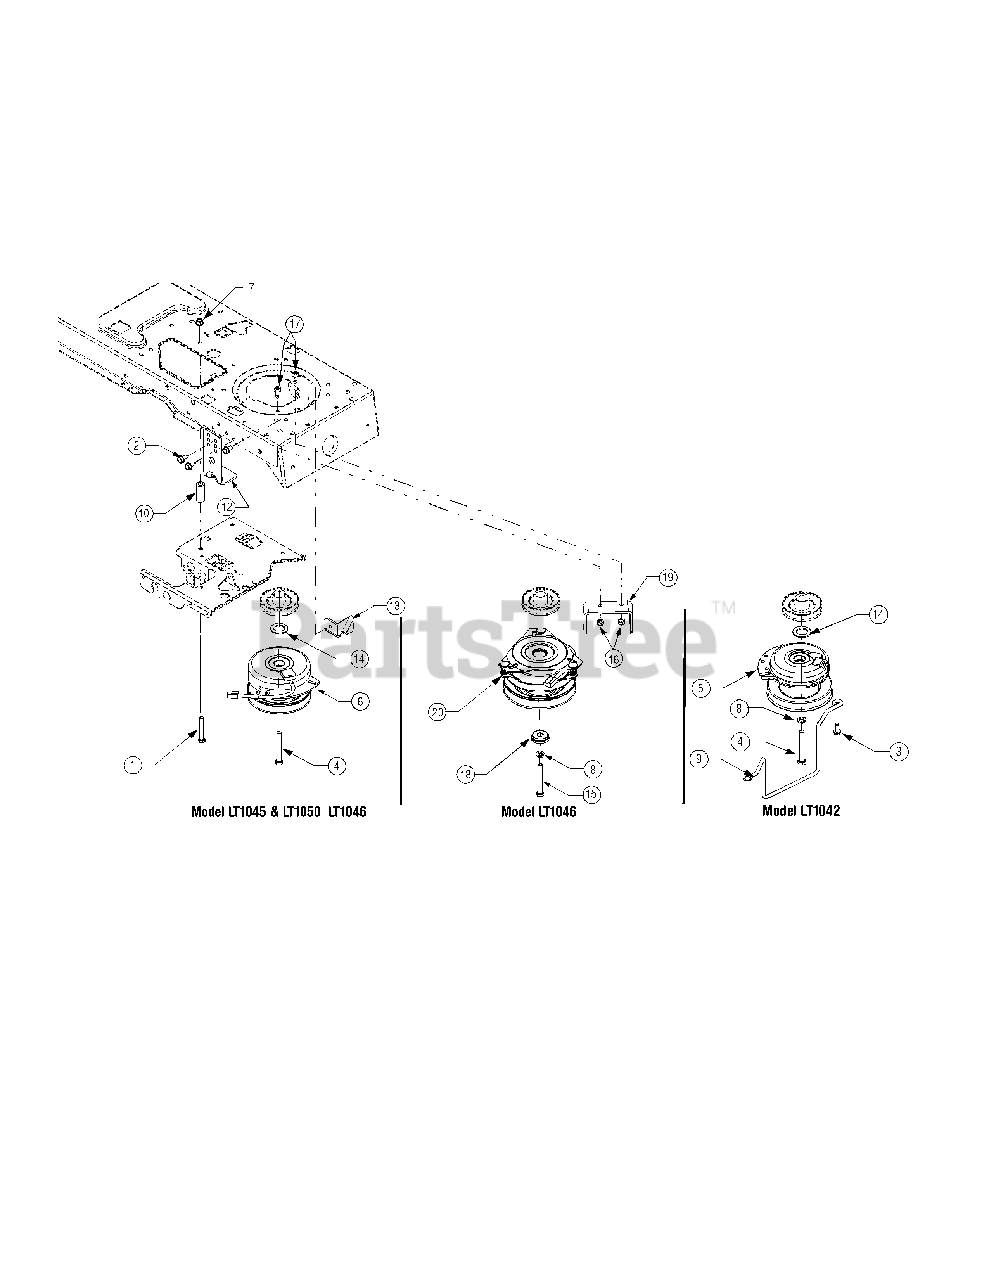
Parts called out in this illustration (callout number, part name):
1	Screw, 3/8-16 x 2.5 GR5
2	Screw, 5/16-12, .75
3	Screw, 5/16-18, .875
4	Screw, Hex Cap, 7/16-20 x 3.25 GR5
4	Screw, Hex Cap, Lock, 7/16-20 x 3.5 GR5
5	Clutch, PTO
6	Clutch, PTO
7	Nut, Hx. Nylon Lock, 3/8-16
8	Washer, Lock, 7/16, Regular Duty
9	Rod, Belt Keeper
10	Spacer, 3/8 x 1.54
11	Washer, Flat, 1.031 x 1.62 x .095
14	Washer, Flat, 1.031 x 1.62 x .095
15	Screw, Hex Cap, 7/16-20 x 2.50 GR5
16	Nut, Lock, Hex, 5/16-18
17	Screw, Hex Cap, 5/16-18 x.625 GR5
18	Shoulder Spacer, 1.38 x.445 x.36
